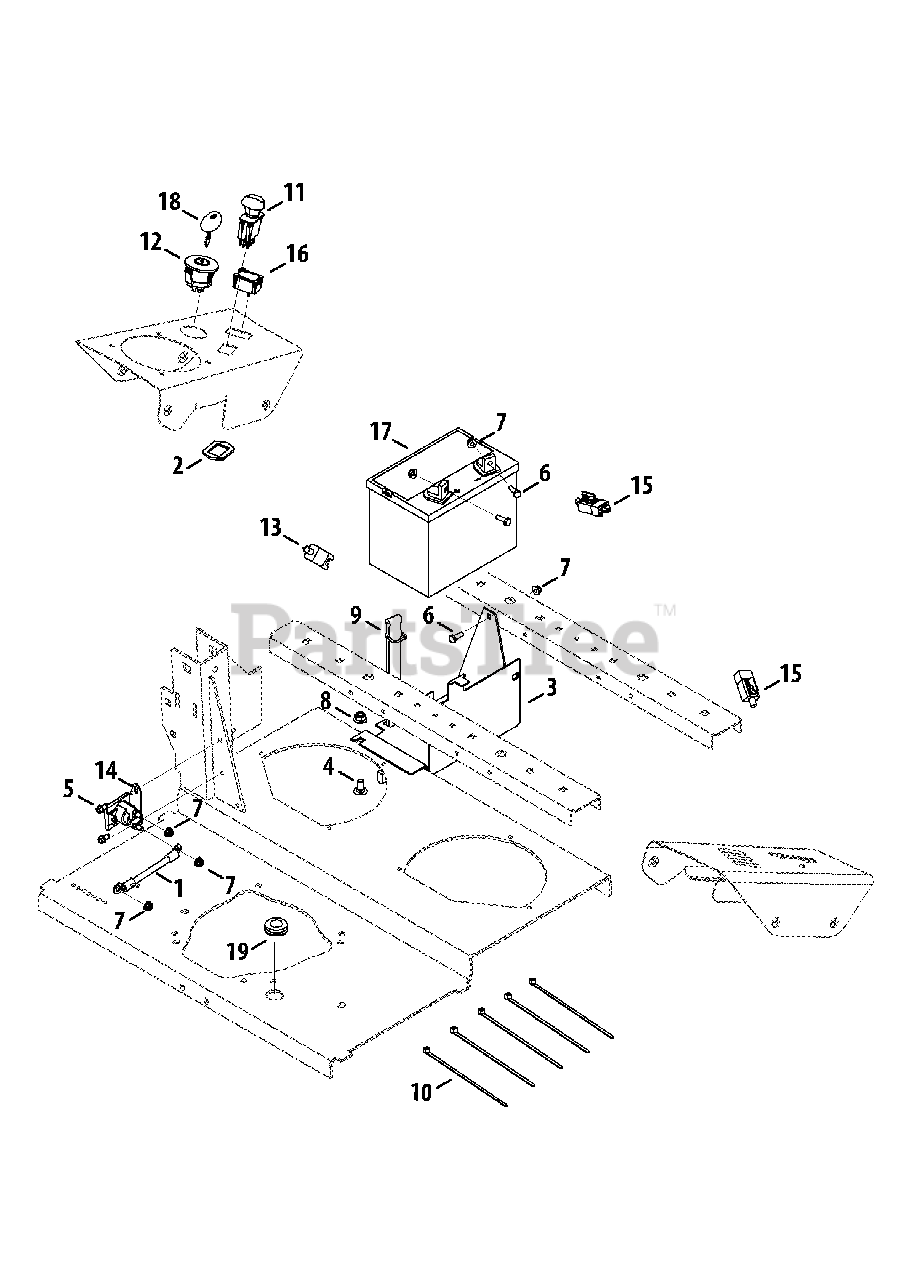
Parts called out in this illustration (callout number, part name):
1	Battery Cable, Red
2	PTO Switch Bracket
3	Battery Bracket
4	Carriage Bolt, 3/8-16 x .750
5	Hex Flange Screw, 1/4-20 x .500
6	Hex Cap Screw, 1/4-20 x .75
7	Nut, 1/4-20, Flangelock
8	Nut, 3/8-16, Flangelock
9	Battery Strap
10	Cable Tie
11	Electric PTO Switch
12	Key Switch
13	Switch, NC/NO/NO
14	Solenoid
15	Plunger Switch, NO/NC
16	Hour Meter
18	Key, Assembly
19	Rubber Grommet, .75 x 1.062 x .50
